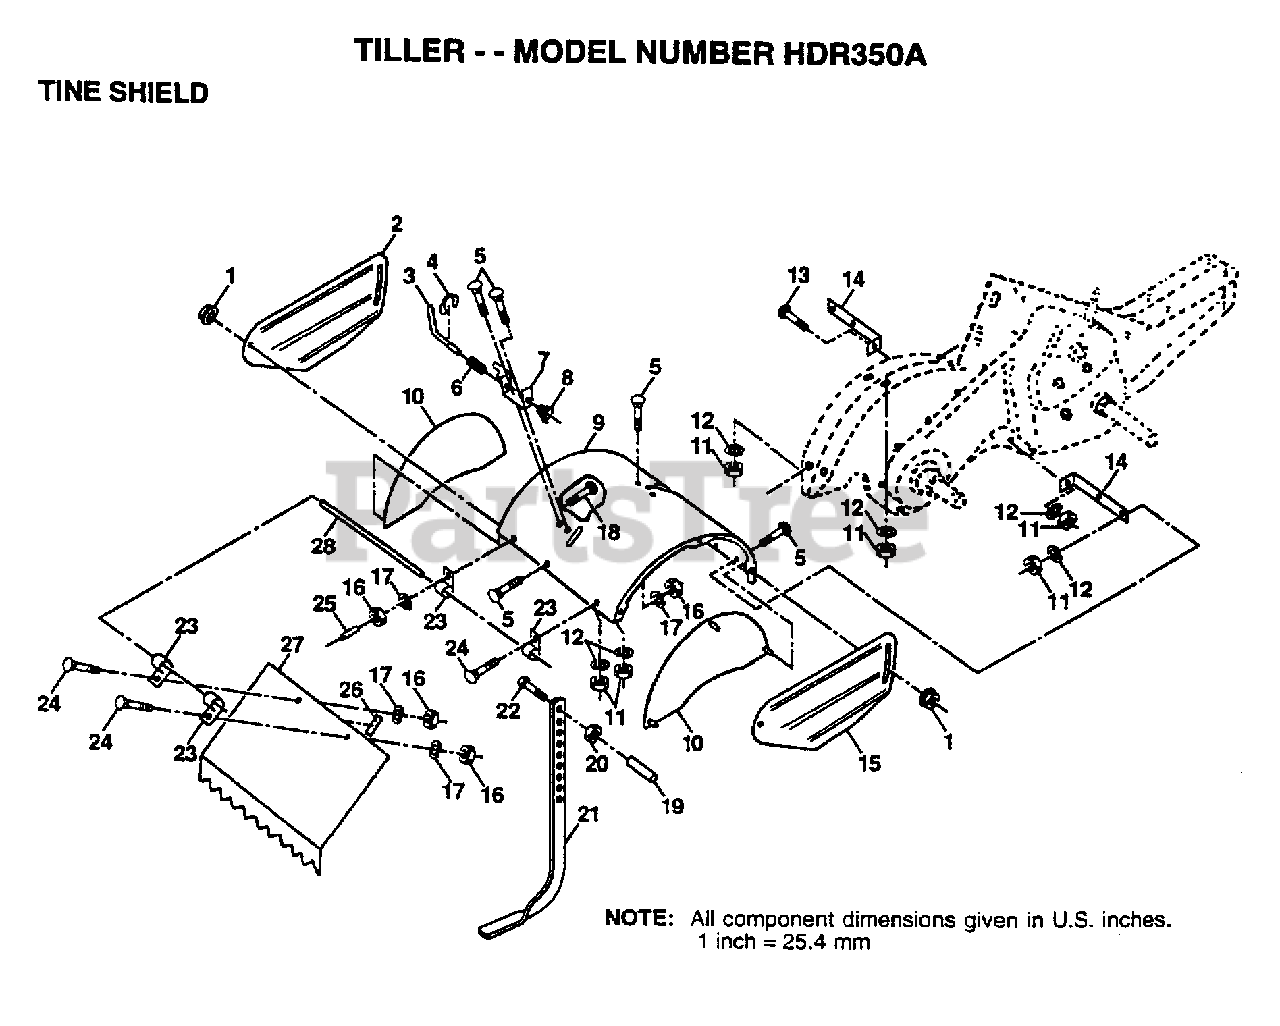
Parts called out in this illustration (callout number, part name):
1	NUT
2	SHIELD.OUT.SD.LH.
3	STAKE PIN TI
4	KLIP RING TI
5	BOLT
6	SPRING TI
7	LATCH BRACKET TI
8	SPRING CRT
9	SHIELD.TINE.PNT.
10	SHIELD.SD.INNER
11	NUT.HEX.5/16-18
12	LOCKWASHER
13	BOLT
14	BRKT SHIELD TINE
15	SHIELD.OUT.SD.RH.
17	LOCKWASHER
18	BOLT
19	GRIP CRT
20	NUT.HEX.3/8-16UNC
21	STAKE DEPTH 16
22	BOLT
23	HINGE CRT
24	BOLT
25	VINYL CAP TI
26	PAD IDLER TI
27	SHIELD.PNT.LEVEL
28	PIN HINGE
